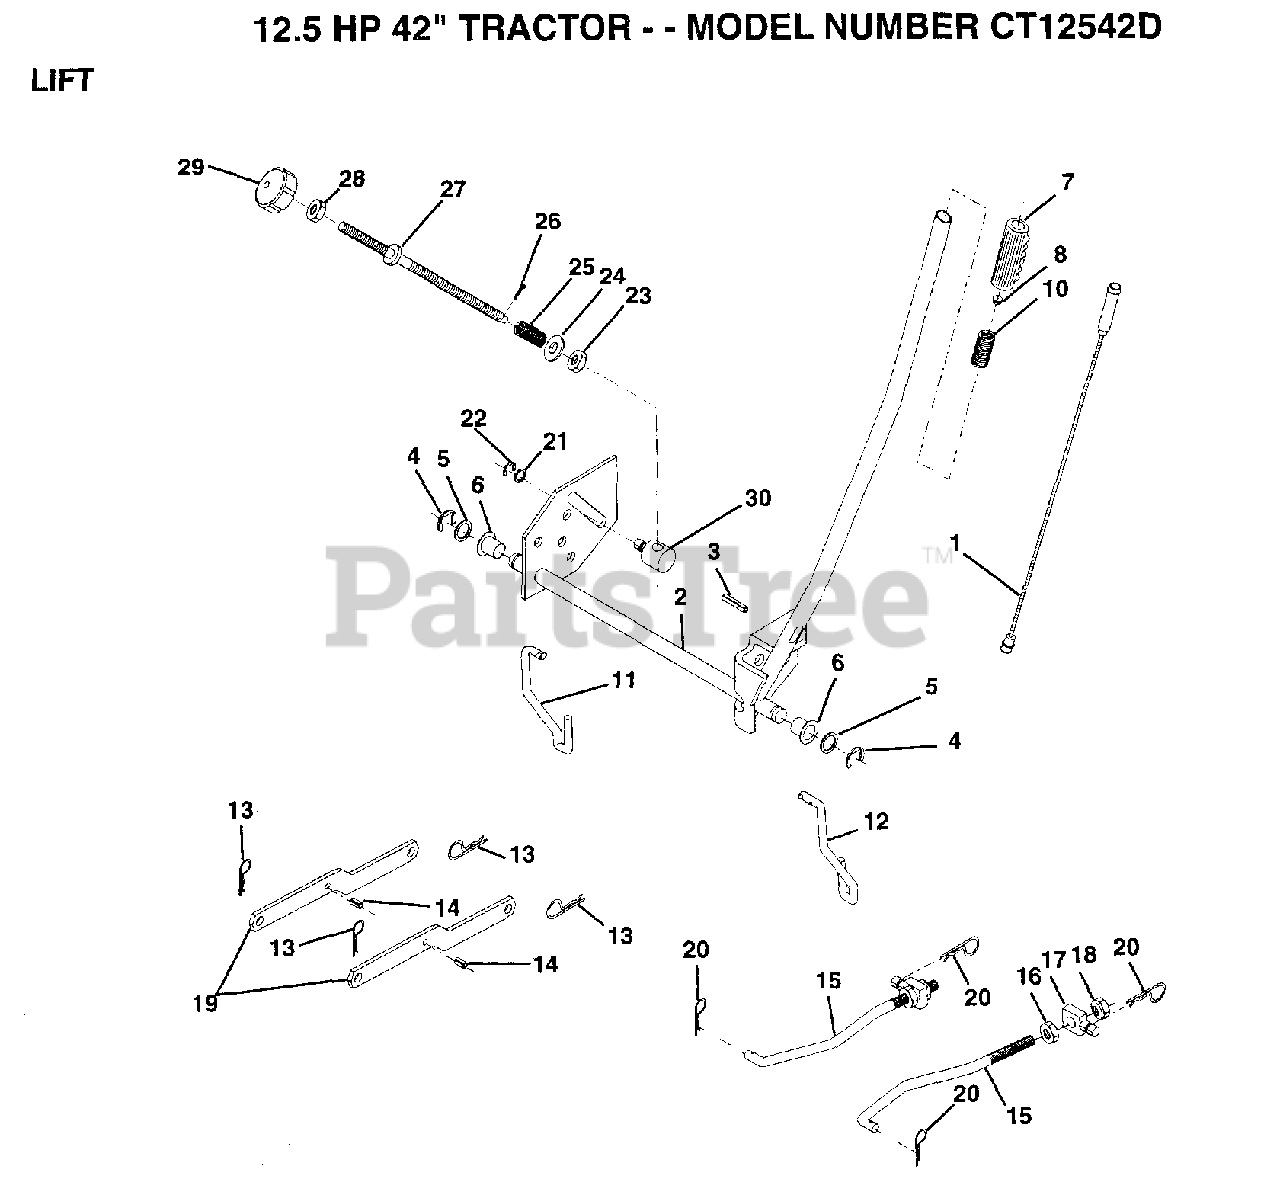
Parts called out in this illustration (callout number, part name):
1	WIRE ASM
3	PIN-GROOVE LT
5	WASHER
6	NYLON BEARING
7	GRIP
11	LINK LIFT LH
12	LIFT LINK RH
14	"PIN,SPRING"
15	LINK.FRONT
16	NUT
17	TRUNION
18	NUT.LK.W/WSH.1/2.
19	SUSP ARM ASM REAR
20	RETAINER.SPRING
21	WASHER
22	KLIP RING
23	NUT T
24	WASHER
25	SPRING T
28	NUT
29	KNOB INF 3/8-16
30	TRUNION LT
